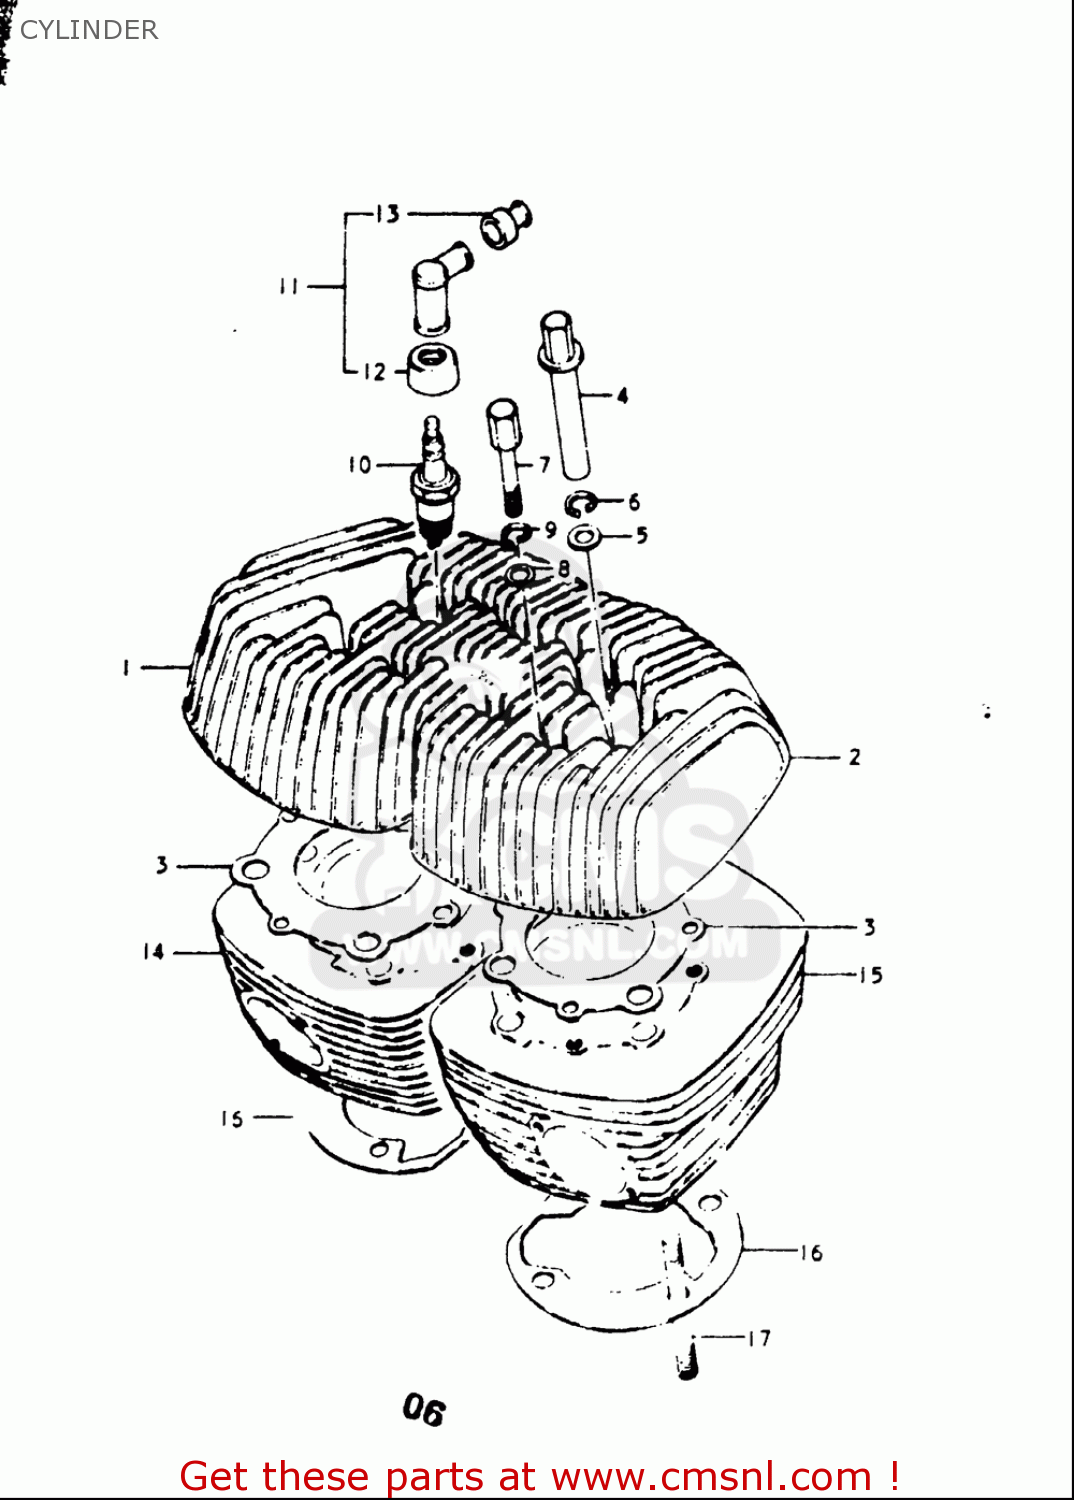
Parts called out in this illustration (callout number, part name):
3	GASKET,CYLINDER HEAD (NAS)
4	NUT (10MM)
5	WASHER
6	WASHER,LOCK
8	WASHER
9	WASHER,LOCK
10	PLUG,SPARK(B7HS)
11	CAP,SPARK PLUG
12	SEAL,SPARK PLUG
13	SEAL,HIGH TENSION CORD
16	GASKET,CYLINDER (NAS)
17	STUD BOLT
